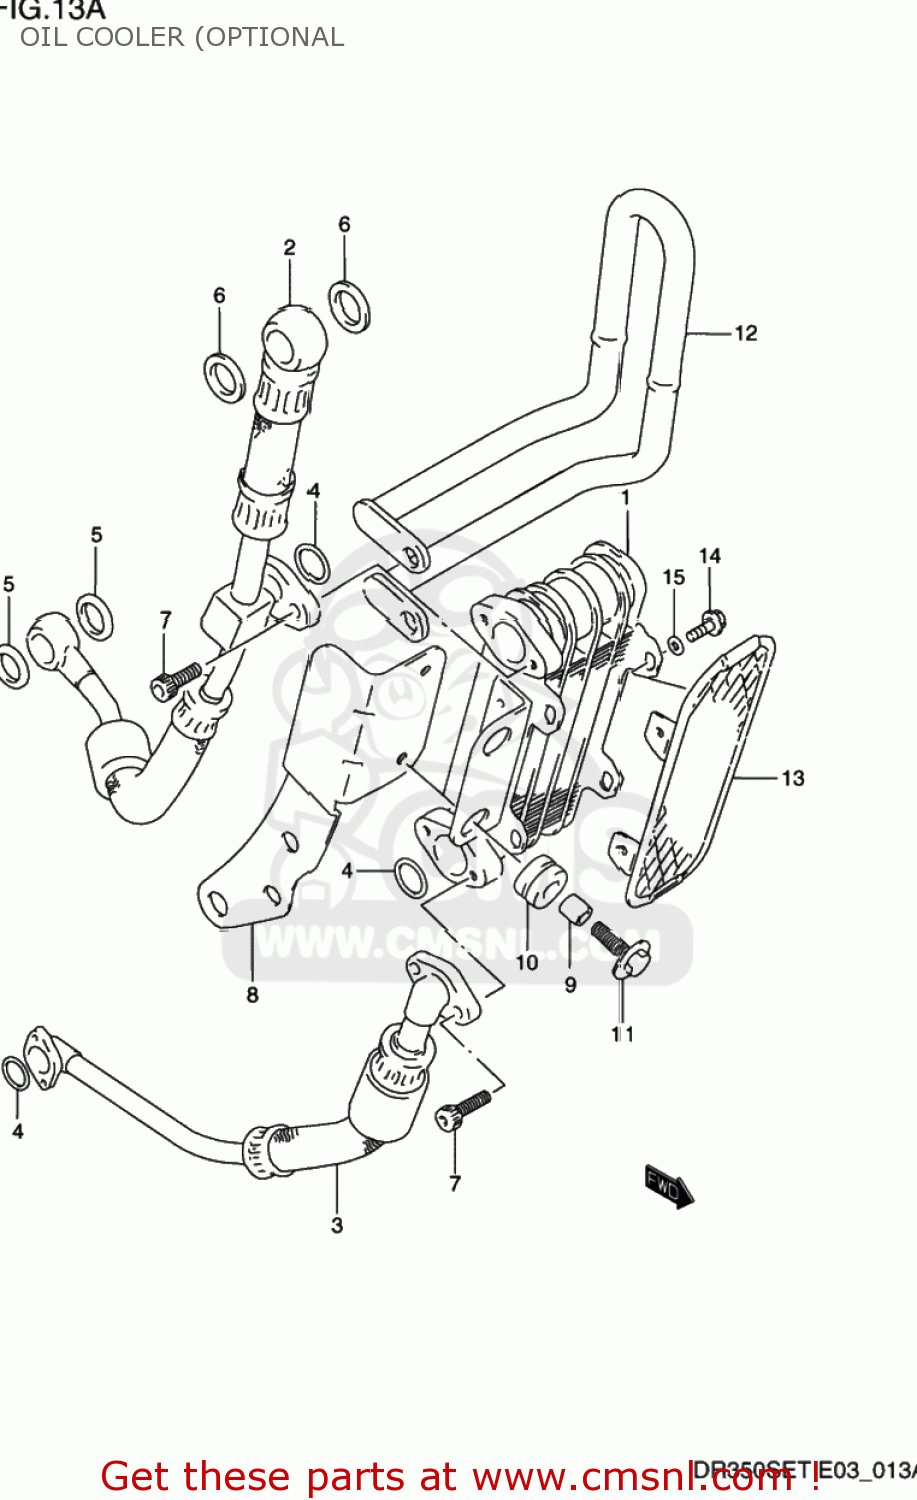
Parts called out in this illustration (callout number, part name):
1	COOLER ASSY,OIL
2	HOSE,OIL COOLER UPR
3	HOSE,OIL COOLER LWR
4	O RING(D:2.4,ID:12.3)
5	GASKET(12X17X1) (NAS)
6	GASKET(16X22X2) (NAS)
7	BOLT
8	BRACKET,OIL COOLER
9	SPACER (6.8X10X10)
10	CUSHION
11	BOLT 6X20
12	GUARD,OIL COOLER
13	BUMPER,OIL COOLER
14	BOLT
15	WASHER,LOCK
